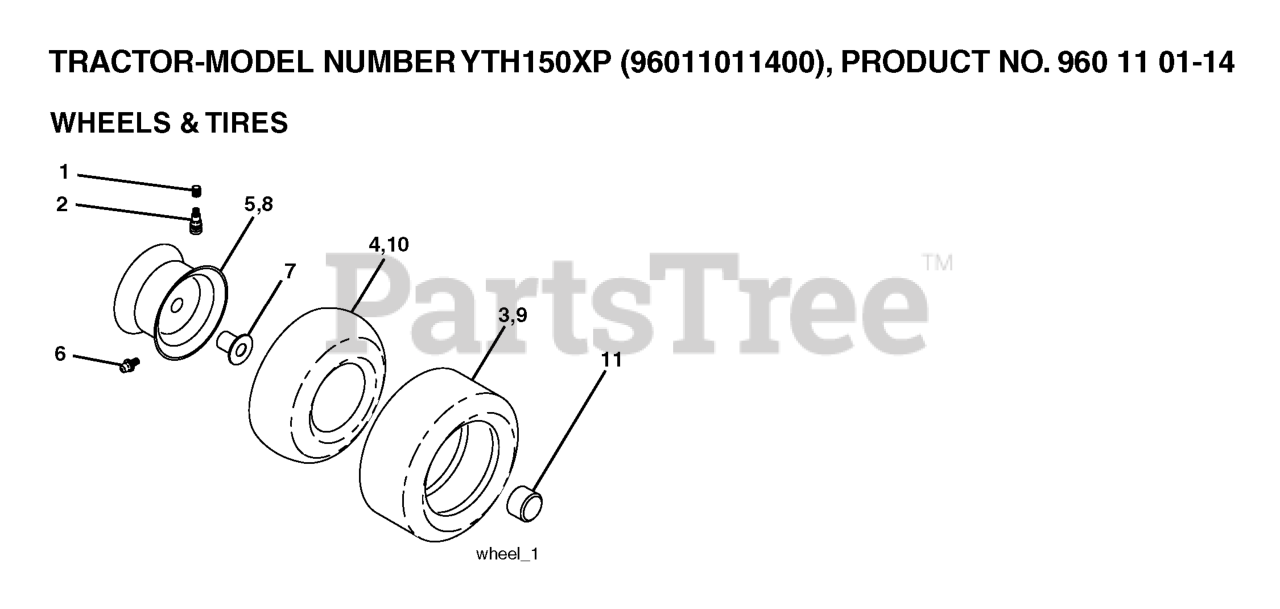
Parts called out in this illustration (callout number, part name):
2	VALVE STEM LT
3	TIRE HEAVY DUTY
4	TUBE.5.3/4.5/6
5	RIM ASM 6" FRONT SILVER
6	FITTING LT
7	BEARING T
8	RIM ASM 8" REAR SILVER
9	TIRE.TS.20X10-8
10	TUBE
11	CAP, AXLE BLK
